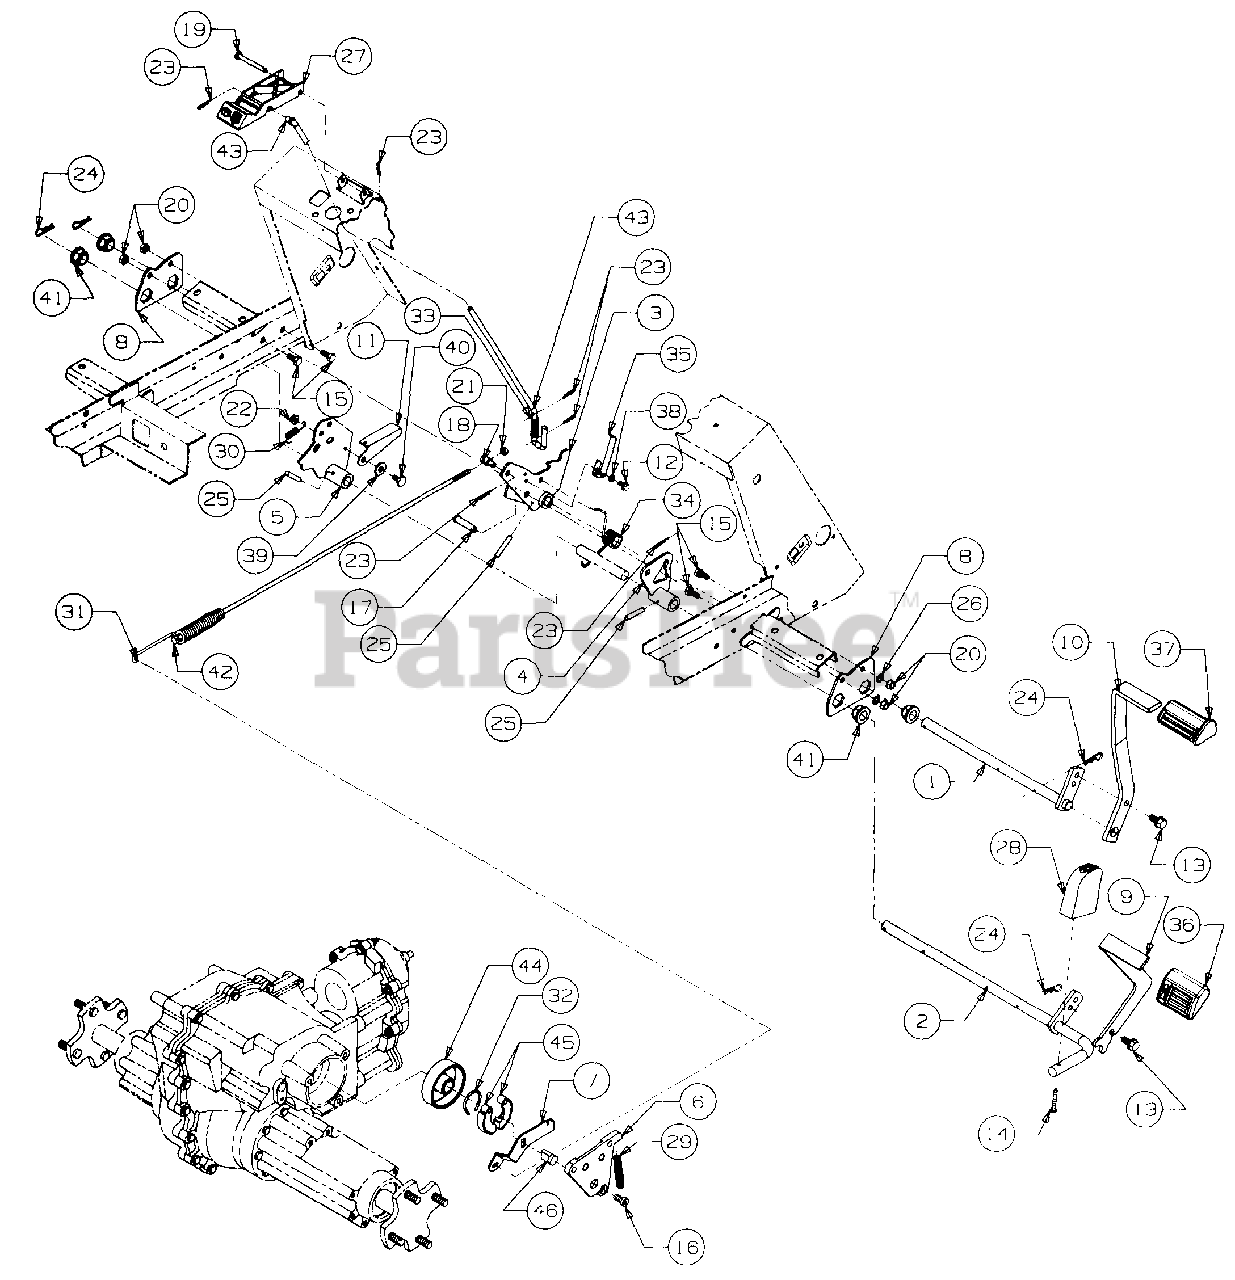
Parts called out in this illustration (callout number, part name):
1	Shaft Assy, Brake
2	Shaft Assy, Clutch
7	Arm, Brake
8	Plate, Pedal Mounting
11	Actuator, Reverse Switch
12	Screw, Hex Wash Tapp 1/4 x .50 Lg
13	Screw, Hex Wash TT-Tapp, 3/8-16 x .75 Lg
14	Screw, Truss Wash Tapp, #12 x 1.5 Lg
15	Screw, Hex Cap, 5/16-18 x .75 Lg GR5
16	Screw, Low Hd Cap, 3/8-16 x .75 Lg
17	Pin, Clevis, 3/8 OD x 1.62 Lg
18	Ferrule, Adjustment
19	Pin, Clevis, 1/4 OD x 2.38 Lg
20	Hex Sems, 5/16-18 Nut
21	Hex Sems, 1/4-20 Nut
22	Nut, Hex Flange Lock, 1/4-20
23	Internal Cotter, 5/16 Dia x 1.12 Lg Pin
24	Internal Cotter, 3/8 Dia x 1.625 Lg Pin
25	Pin, Spiral Spring, 1/4 Dia x 1.5 Lg
26	Nut, Push Speed, 5/16 ID
27	Lever, Park Brake
28	Pad, Reverse Pedal
29	Spring, Compression
30	Spring, Extension, .38 OD x 2.10 Lg
31	Spring, Extension, .75 OD x 5.0 Lg
32	Spring, Brake
33	Spring, Compression, .50 OD x 2.23 Lg
34	Spring, Torsion
35	Actuator, Neutral Switch
36	Pad, Forward Pedal
37	Pad, Brake Pedal
38	Washer, Flat, .281 x .50 x .063 Thk
39	Washer, Flat, .406 x .75 x .063 Thk
40	Bolt, Shoulder, .375 Dia x .181 Lg
41	Bearing, Hex Flange
42	Rod, Brake
43	Rod, Park Brake Engagement
44	Drum, Brake
45	Shoe, Brake
46	Actuator, Brake Shoe
